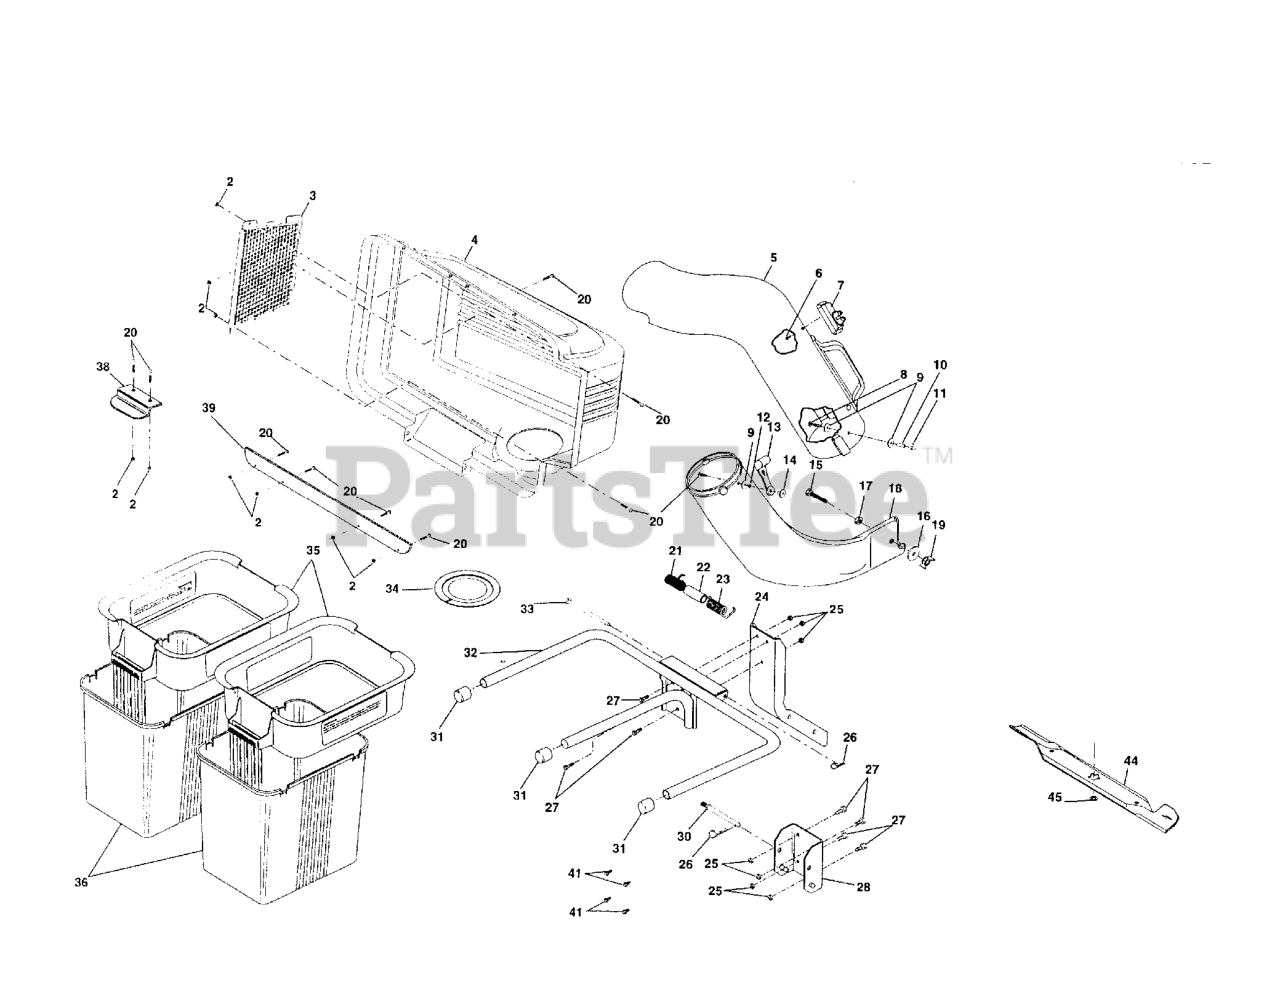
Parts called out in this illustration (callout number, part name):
3	COVER SCREEN
4	COVER
5	CHUTE, UPPER
7	INDICATOR DUMP BAG
8	SCREW
11	NUT
12	LOCKWASHER #10
13	LATCH.HOOD.
14	WELDNUT
15	Bolt, Hex Head 3/8-16 x 1-1/4
16	WASHER
17	LOCKNUT
18	CHUTE.LOWER.38"
20	SCREW
21	SPRING COVER LH
22	SPACER.COVER.BAGGER
23	SPRING COVER RH
24	POST, SUPPORT
26	RETAINER-SPRNG RB
27	BOLT
28	MTG BRACKET
30	SUPPORT POST PIN
31	TUBING PLUG
32	BAGGER FRAME
33	HINGE PIN
34	GASKET.COVER.BAGGER
35	CONTAINER TOP
36	CONTAINER BOTTOM
38	LATCH CER38
39	STRIP.REINFORCE.BAGGER.2BIN.BL
41	Screw 5/16-18 x 1/2 Hex, Self Tapping 5/16-18 x 1/2
44	BLADE.HI.LIFT.38"
